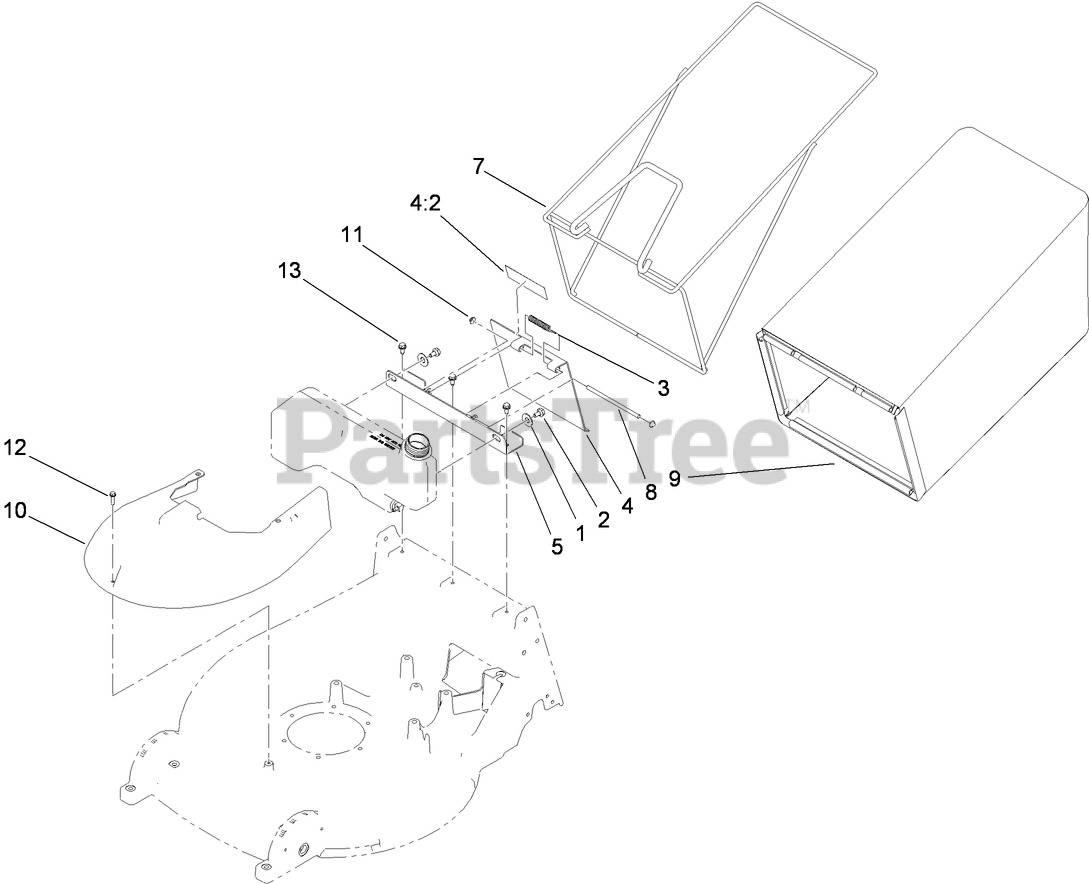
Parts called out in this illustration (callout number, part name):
1	WASHER-PLASTIC
2	BOLT-SHOULDER
3	SPRING-TORSION
4	DOOR ASM
4:2	DECAL-DANGER
5	BRACKET-MOUNT, BAG/DOOR
7	FRAME-BAG
8	ROD-PIVOT, DOOR
9	GRASS BAG ASM
10	COVER-SPINDLE
11	NUT-PUSH
12	SCREW-HWHTF
13	SCREW-HWHTF
